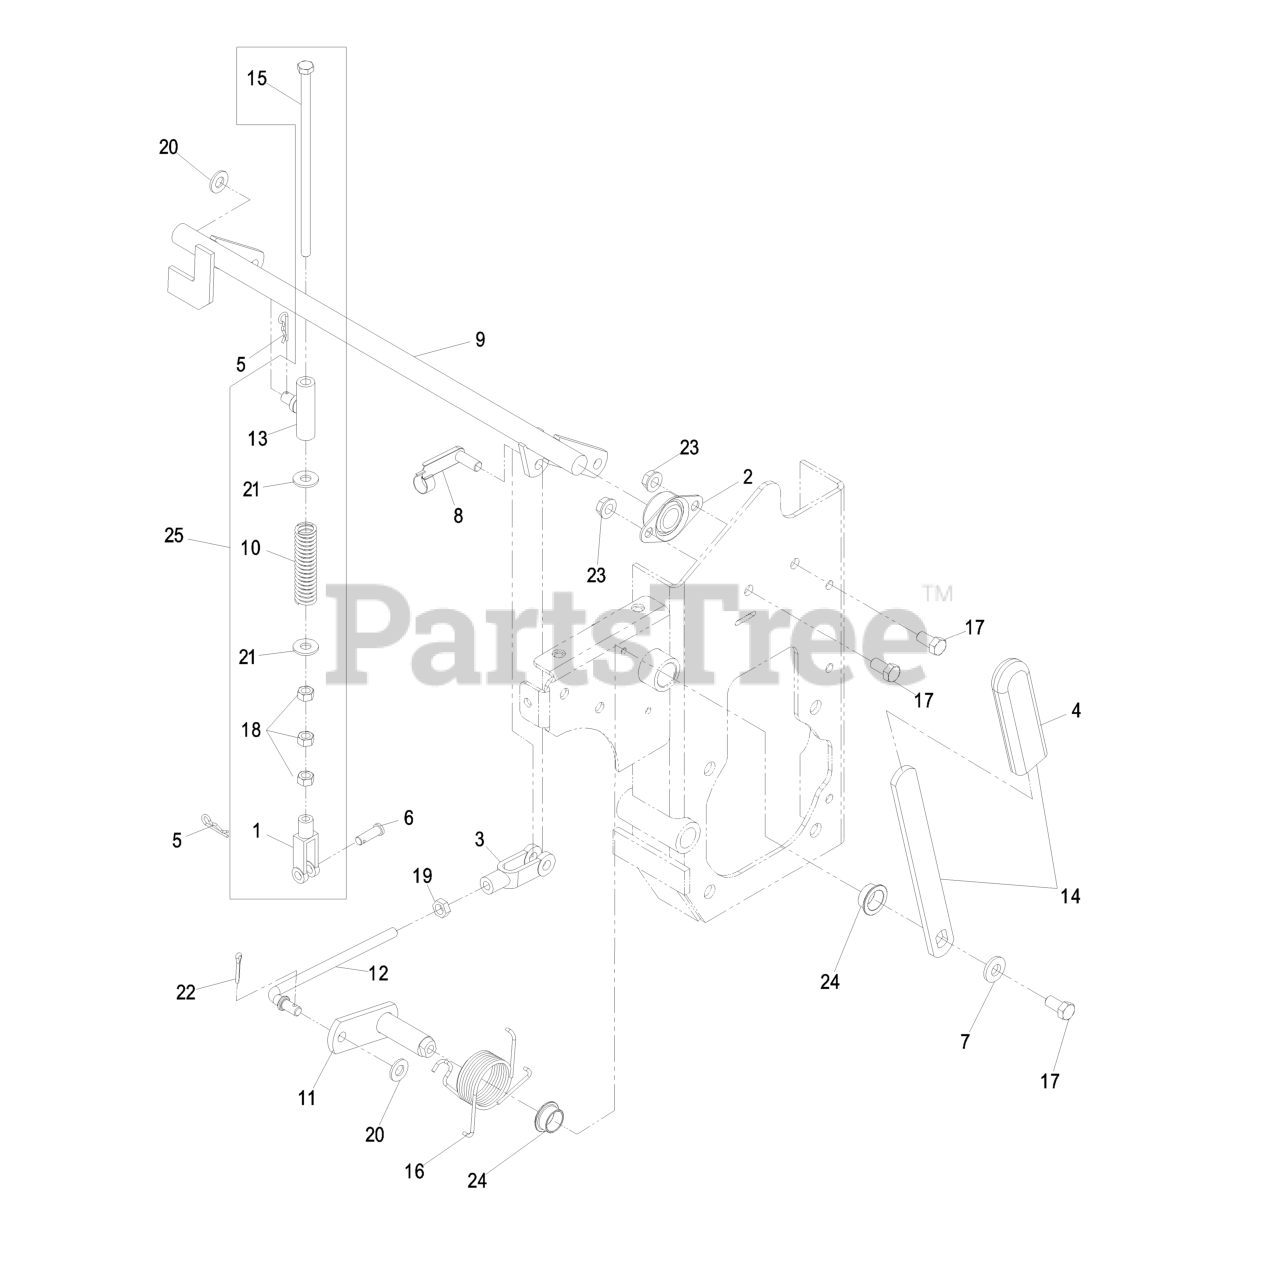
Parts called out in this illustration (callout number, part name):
1	YOKE-ADJUSTABLE
2	BEARING-FLANGE, SIDE
3	YOKE-LINKAGE, BRAKE
4	GRIP-LEVER
5	PIN-COTTER
6	PIN-CLEVIS
7	WASHER-BELLEVILLE
8	PIN-SPRING, CLEVIS
9	WLD, BRAKESHAFT
10	SPRING,COMPRESSION
11	WLD,BRAKE PIVOT (PLATED)
12	ROD,LINKAGE BRAKE (PLATED
13	WLD,SWIVEL BRAKE (PLATED)
14	PARK BRAKE HANDLE ASM
15	SCREW-HH
16	SPRING,TORSION RH
17	SCREW-HH
18	NUT-HEX
19	NUT-HEX
20	WASHER-FLAT
21	WASHER-FLAT
22	PIN-COTTER
23	NUT-HHF, WHIZ
24	BUSHING-BRONZE
25	ASM,BRAKE LINKAGE
